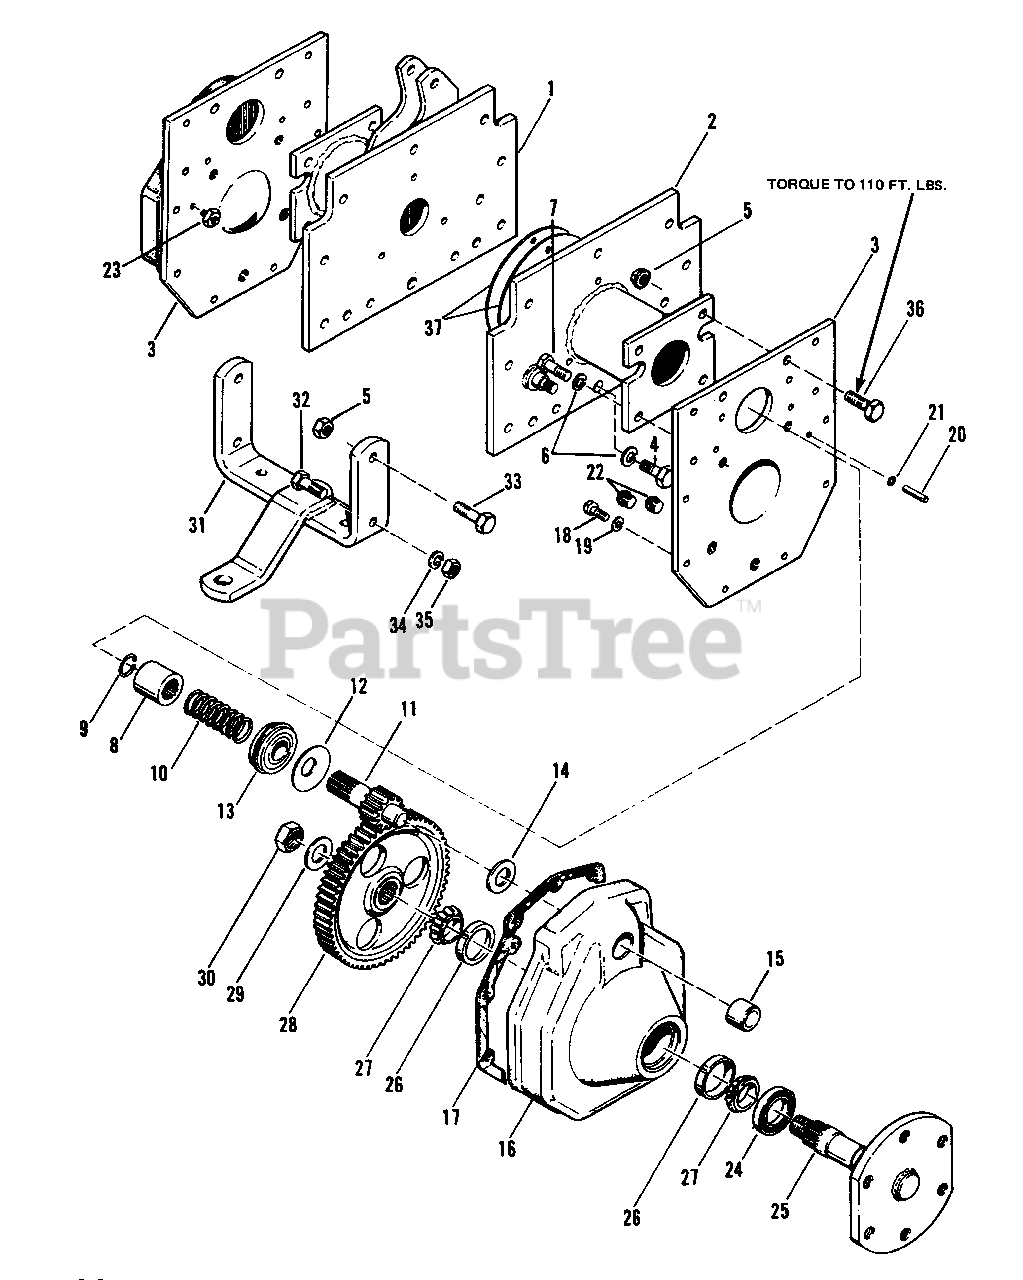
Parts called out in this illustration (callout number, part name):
1	Axle Extension, L.H.
2	Axle Extension, R.H.
3	Housing Plate
4	Hex Capscrew, 1/2"-13 x 1-1/2" lg.
5	Hex Nut, Lock
6	Lock Washer, 1/2"
7	Hex Capscrew, 1/2"-13 x 1" lg.
8	Axle Couple
9	Retaining Ring
11	Bull Pinion
13	Rear Axle Bearing
14	Thrust Washer
15	Roller Bearing
16	Drop Housing
18	Hex Capscrew
19	Lock Washer, 3/8"
22	Pipe Plug
23	Relief Valve
25	Rear Axle Assembly
26	Bearing Cup
27	Bearing Cone
28	Bull Gear
29	Plain Washer
32	Hex Capscrew, 1/2"-13 x 1-1/2" lg.
33	Hex Capscrew, 1/2"-13 x 1-3/4" lg.
34	Lock Washer, 1/2"
35	Hex Nut, 1/2"-13
36	Hex Capscrew, 1/2"-13 x 1-1/2" lg.
37	Shim Plate
